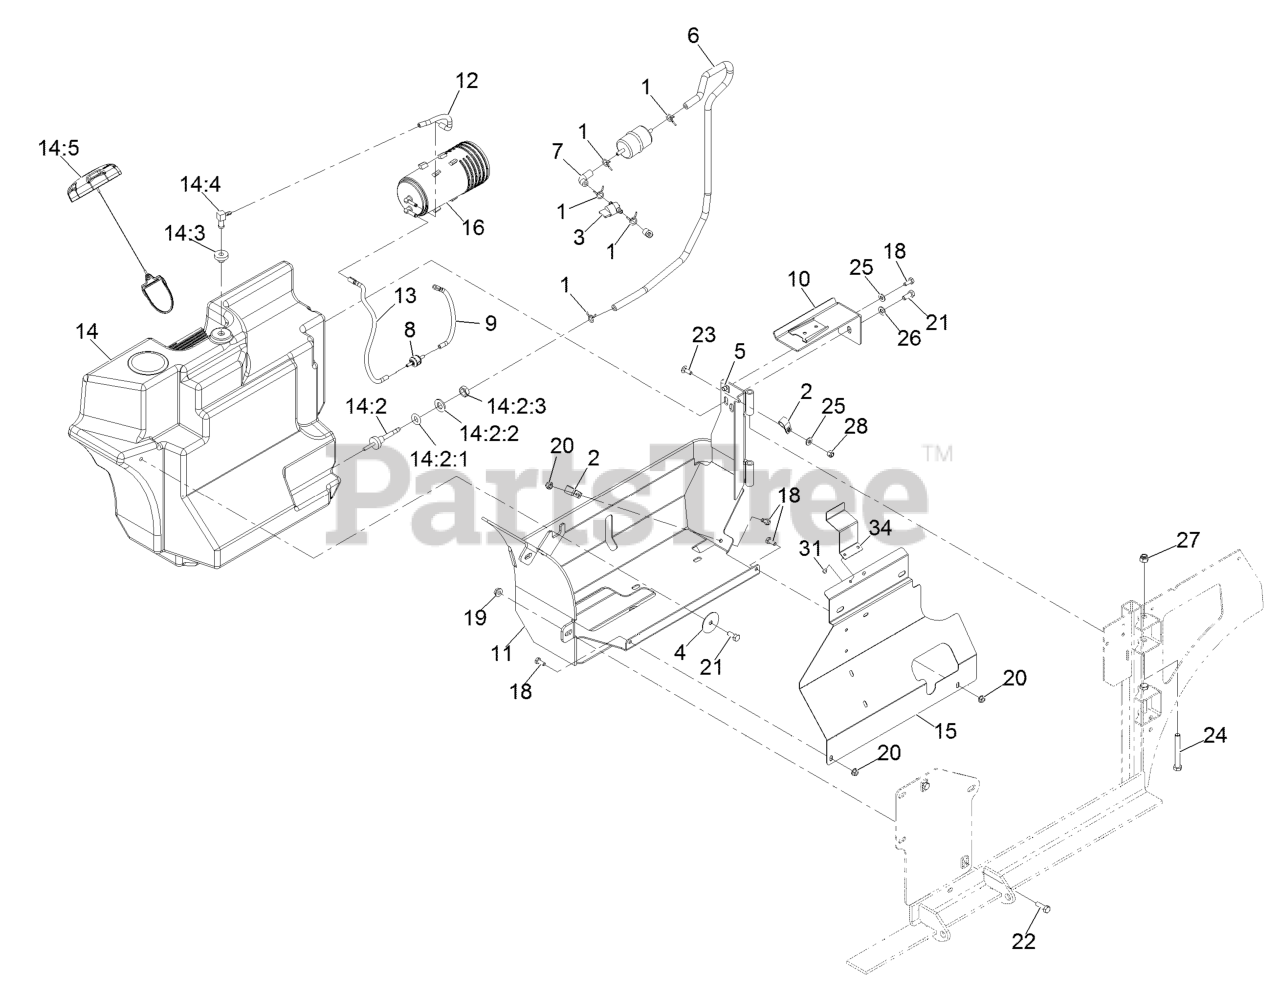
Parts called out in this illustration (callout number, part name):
2	CLIP-LOOM
3	VALVE-FUEL
5	Nut-Retainer-Panel 1/4-20
6	HOSE-FUEL
7	HOSE-FUEL
9	HOSE-VENT, FORMED
10	CANISTER BRACKET ASM
11	TANK FRAME ASM
12	HOSE-VENT, FORMED
13	HOSE-VENT, FORMED
14	FUEL TANK ASM
14:2	FITTING-FUEL, BULKHEAD
14:2:1	O-RING,BULKHEAD FITTING
14:2:2	WASHER-FLAT
14:2:3	NUT-JAM
14:3	BUSHING
15	PANEL-TANK SHIELD
16	CANISTER-CARBON, 800CC
18	SCREW-HH
21	SCREW-HH
22	SCREW-HH
23	BOLT-CARR
24	SCREW-CARR
25	WASHER-FLAT
26	WASHER-PLAIN
27	NUT-LOCK, NI
28	NUT-LOCK, NI
31	RIVET-POP
34	BRACKET-SHIELD, TANK
